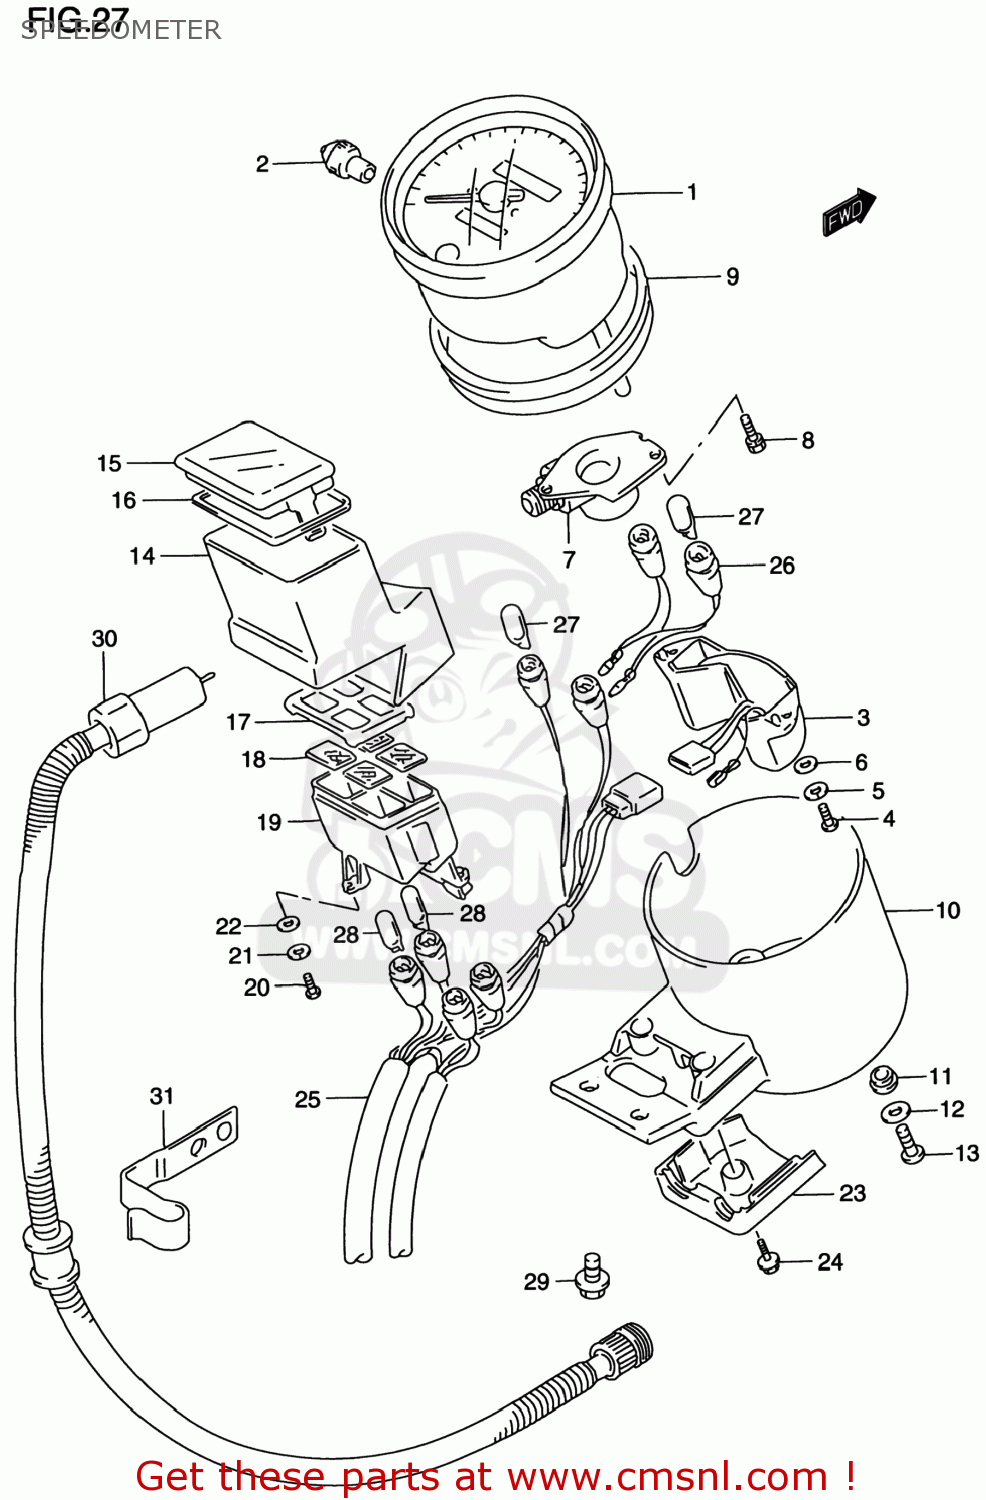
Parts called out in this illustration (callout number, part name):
1	SPEEDOMETER(MILE/KILO)
2	KNOB,TRIP
3	UNIT,WATER TEMP
4	SCREW
5	WASHER,LOCK
6	WASHER
7	BOX,GEAR
8	SCREW
9	CUSHION
10	COVER,METER
11	CUSHION,METER
12	WASHER
13	SCREW
14	BOX,PILOT
15	LENS,PILOT BOX
16	CUSHION
17	PLATE,PILOT LENS
18	LENS SET,PILOT LAMP
19	CASE,PILOT LAMP
20	SCREW
21	WASHER,LOCK
22	WASHER
23	COVER,PILOT BOX
24	SCREW
25	SOCKET,METER NO.1
26	SOCKET
27	BULB(12V3W,T6.5)
28	BULB(12V1.7W,T6.5)
29	SCREW
30	CABLE ASSY,SPEEDOMETER
31	GUIDE,SPEEDOMETER CABLE
